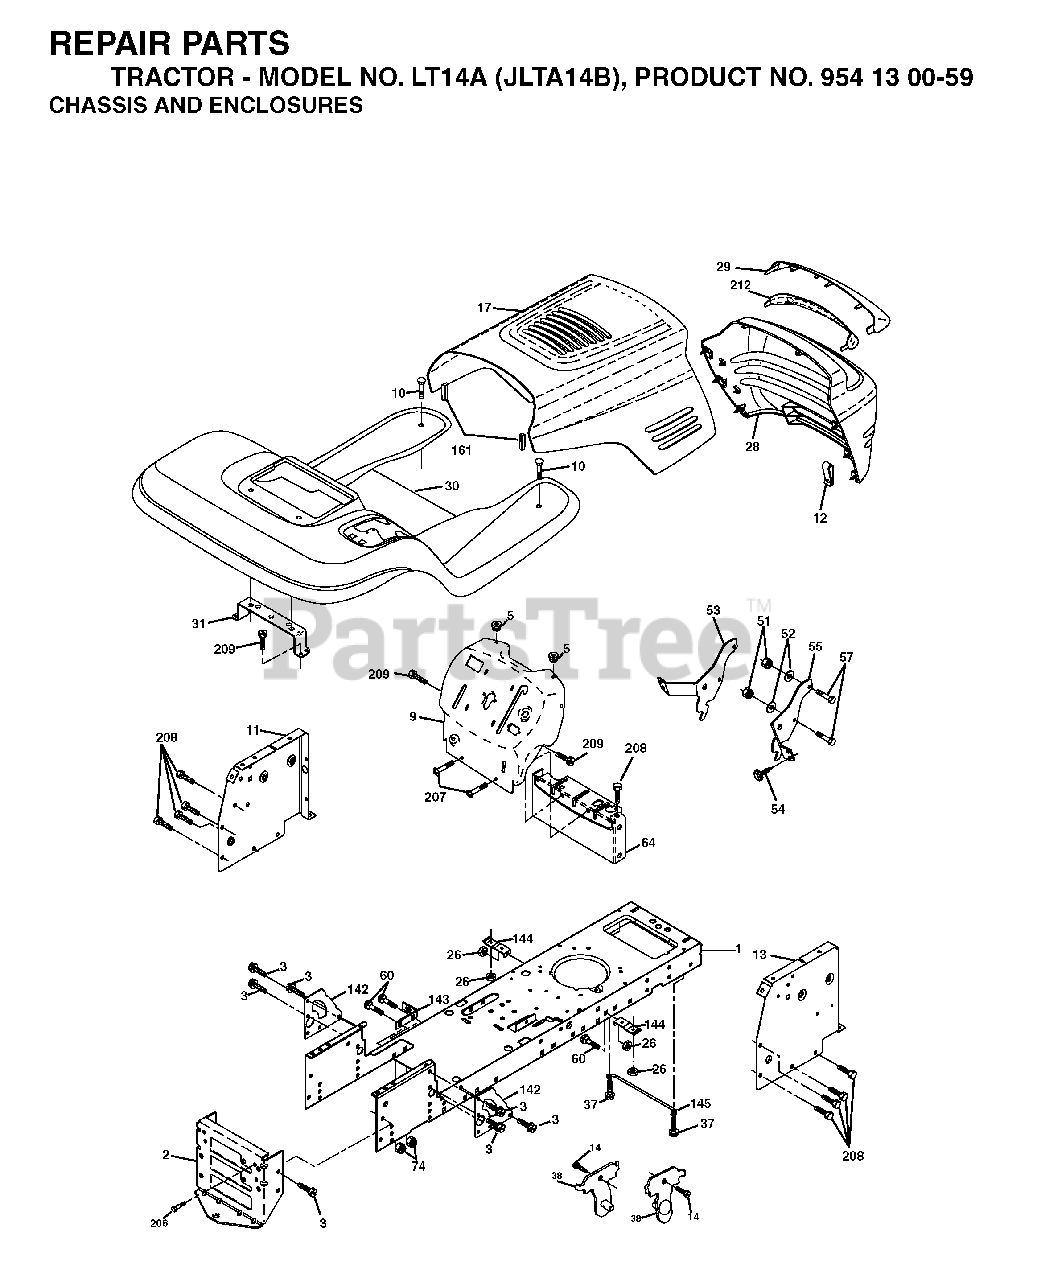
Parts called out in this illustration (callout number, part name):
1	CHASSIS STAMPING
2	DRAWBAR, 12GA
3	SCREW 3/8-16X3/4
5	BUMPER.RUBBER.HOOD
10	BOLT D
11	PANEL.DASH.LH.LTX
13	PANEL DASH RH
26	NUT
38	BRACKET.ASM.PIVOT.MOWER.REAR
51	LOCKNUT
57	BOLT
64	DASH LOWER
74	LOCKNUT
142	PLATE REINFORCEMENT
143	BRACKET, SWAY BAR
144	BRKT, FOOT REST
145	ROD PIVOT CHASSIS/HOOD
161	EXTRUSION BUMPER
206	SHOULDER BOLT 5/16-18TT
207	SCREW, 5/16-18 X 1/2
208	SCREW 3/8-16X1/2
209	SCREW, 3/8-16X3/4
